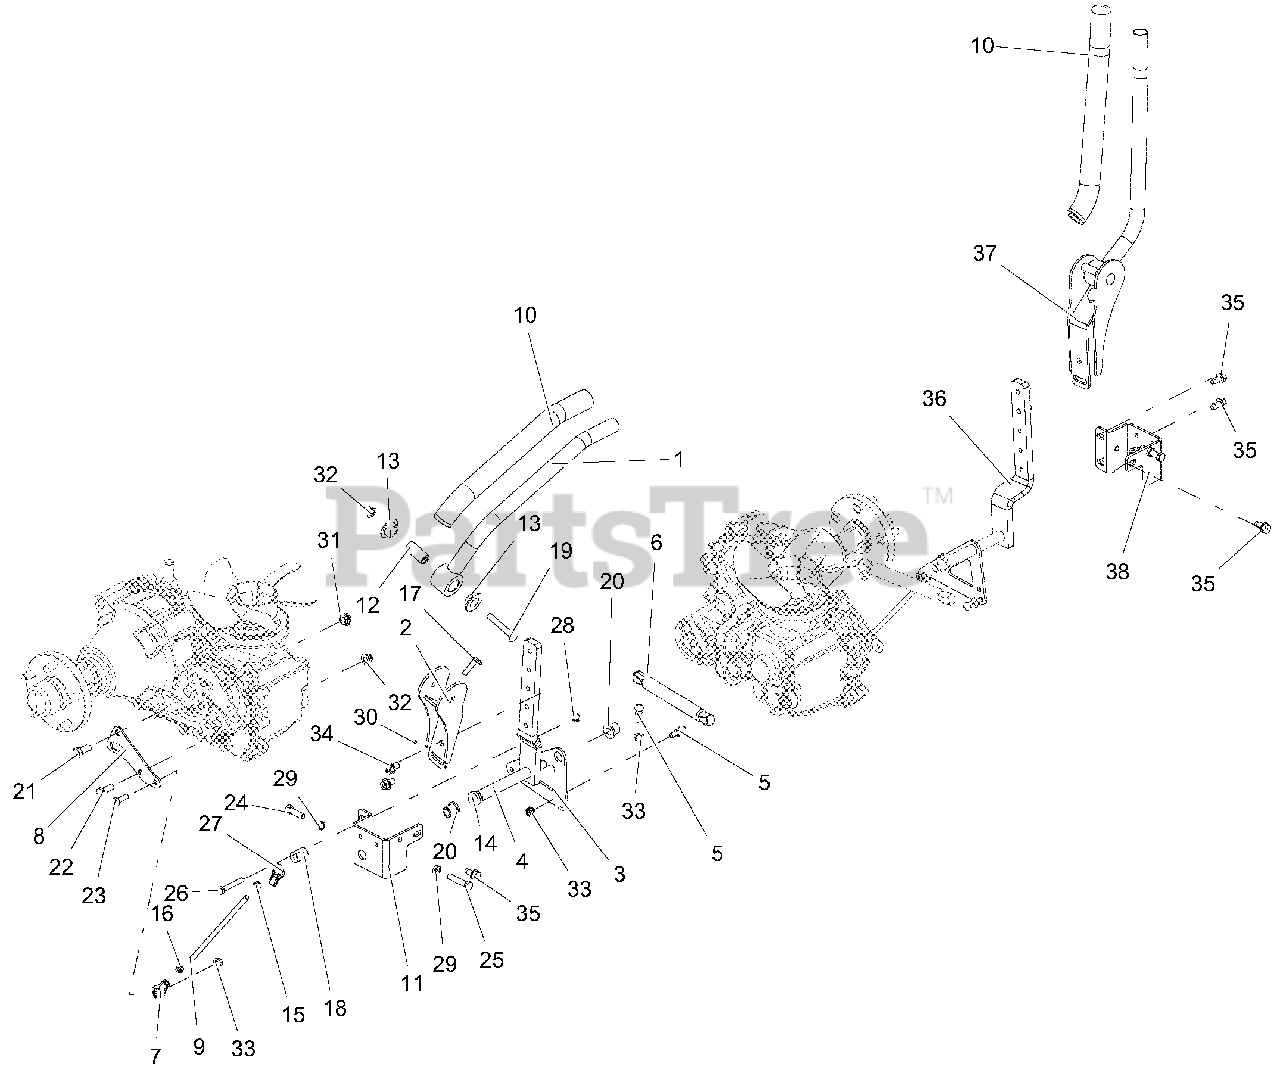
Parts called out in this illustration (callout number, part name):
1	WLDMT, RH STEERING ARM
2	MOUNT, STEERING ARM, ADJUSTABLE-BLACK
3	WLDMT, RH LOWER CONTROL ARM
4	WAVE WASHER .531X.781X.125 FH
5	STUD-BALL
6	DAMPER,
7	ALIGNABALL, 5/16 LH THREAD
8	BRKT., CONTROL MTG-BLACK
9	ROD, STEERING
10	GRIP, HANDLEBAR
11	BRKT, RH CONTROL ARM STOP-RED
12	SPCR, STEERING ARM
13	BSHG, FLANGE .762 X 1.48 X .44 NYLON
15	NUT-JAM
16	NUT, JAM -LH .31-24 YWZC
17	BUMPER, STUD MOUNTED
18	ECCENTCRI
19	BLT-RHDSSQNK .38-16X2.50 G5YZ
20	BHSG-FLG .500X.750X.750X.125
21	BLT-HEX .44-14X1.00 GR5 YWZC
22	BLT-HEX .38-16X1.00 GR5 YWZC
23	BLT-HEX .31-18X1.00 GR5 YWZC
24	BLT-HEX .38-16X1.25 GR5 YWZC
25	BLT-HEX .38-16X1.75 GR5 YWZC
26	BLT-HEX .31-18X2.00 GR5 YWZC
27	ALIGNABALL, 5/16 RH THREAD
28	NUT-LK-CTR .31-18 YCWZ
29	NUT, JAM .375-16 YWZC
30	NUT, JAM .312-18 YWZC
31	NUT-LK-NYL-FLG .44-14 YWZC
32	NUT-LK-NYL-FLG .38-16 YWZC
33	NUT, LK-TOP-FLG .312-18 YWZC
34	BLT-SERHFWH .38-16X.62 YWZC
35	SCR-TAP .38-16X.75 HWH TRZ YW
36	WLDMT, LH LOWER CONTROL ARM
37	WLDMT, LH STEERING ARM
38	BRKT, LH CONTROL ARM STOP-RED
